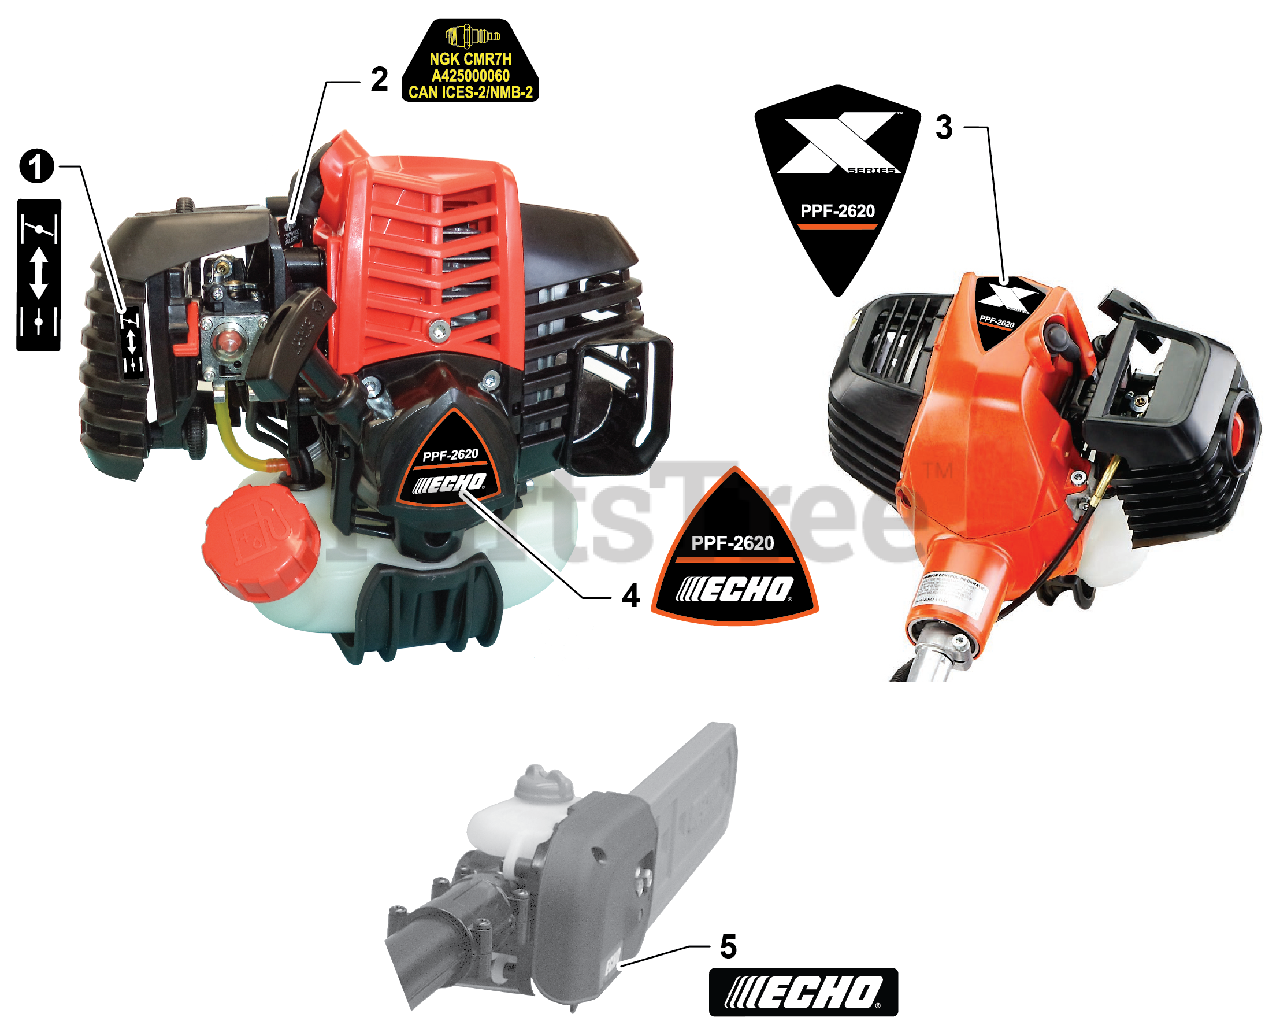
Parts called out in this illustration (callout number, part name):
1	LABEL, CHOKE
2	LABEL, SPARK PLUG - CMR7H
3	LABEL - MODEL PPF-2620
4	LABEL, RECOIL STARTER - PPF-2620
5	LABEL, ECHO
